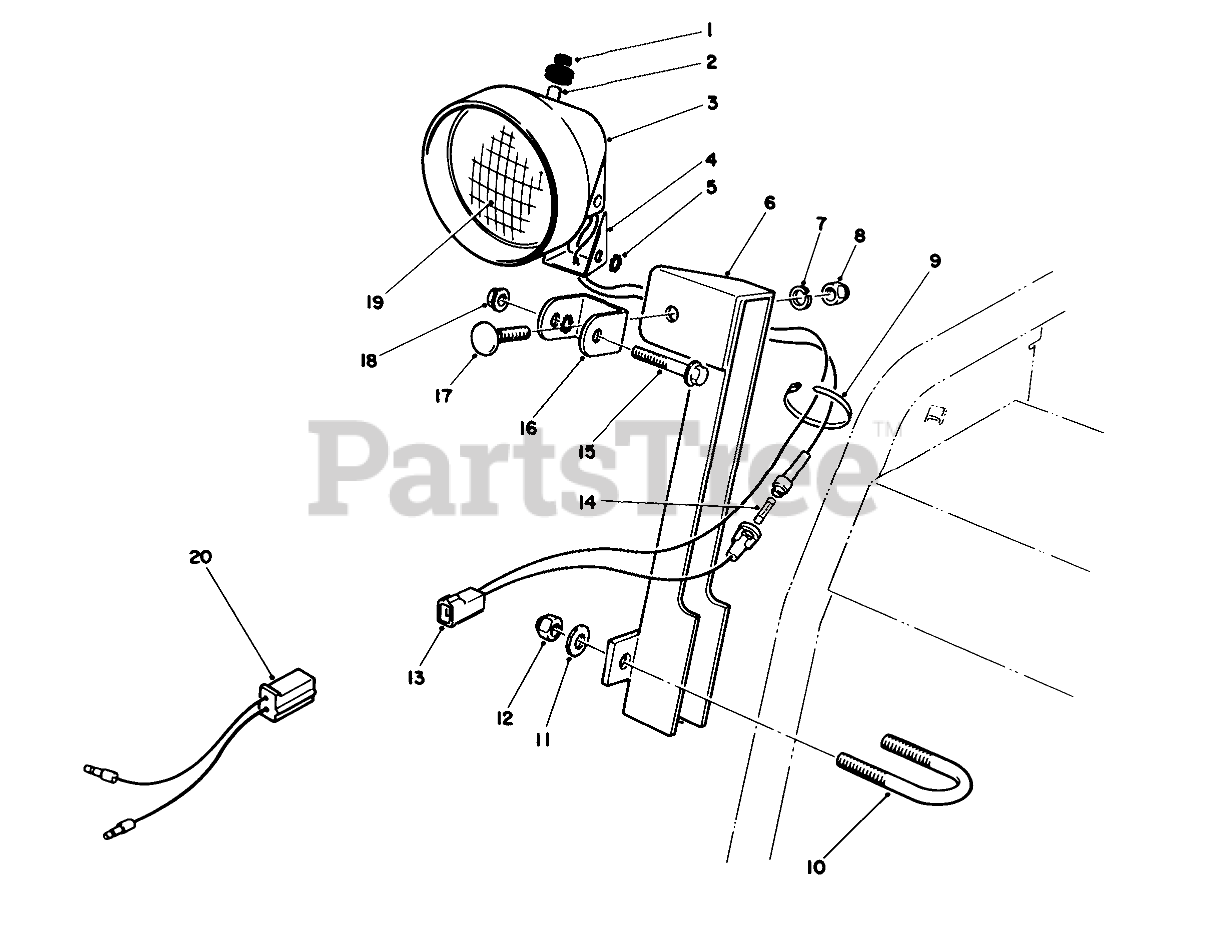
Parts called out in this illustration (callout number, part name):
1	BOOT-SWITCH
2	SWITCH ASM
3	Bucket-Headlamp
4	TO BE DISCONTINED-NOT NEEDED ON PRODUCT
5	WASHER-LOCK
6	Mount-Lamp
7	WASHER-LOCK
8	NUT-HEX
9	TIE-CABLE
10	U-BOLT
11	WASHER-PLAIN
12	NUT-LOCK, NI
13	WIRE ASM
14	Fuse-7-1/2 Amp.
15	SCREW-HH
16	BRACKET
17	BOLT-CARR
18	NUT-HF
19	BEAM-SEALED
20	WIRE ASSEMBLY
